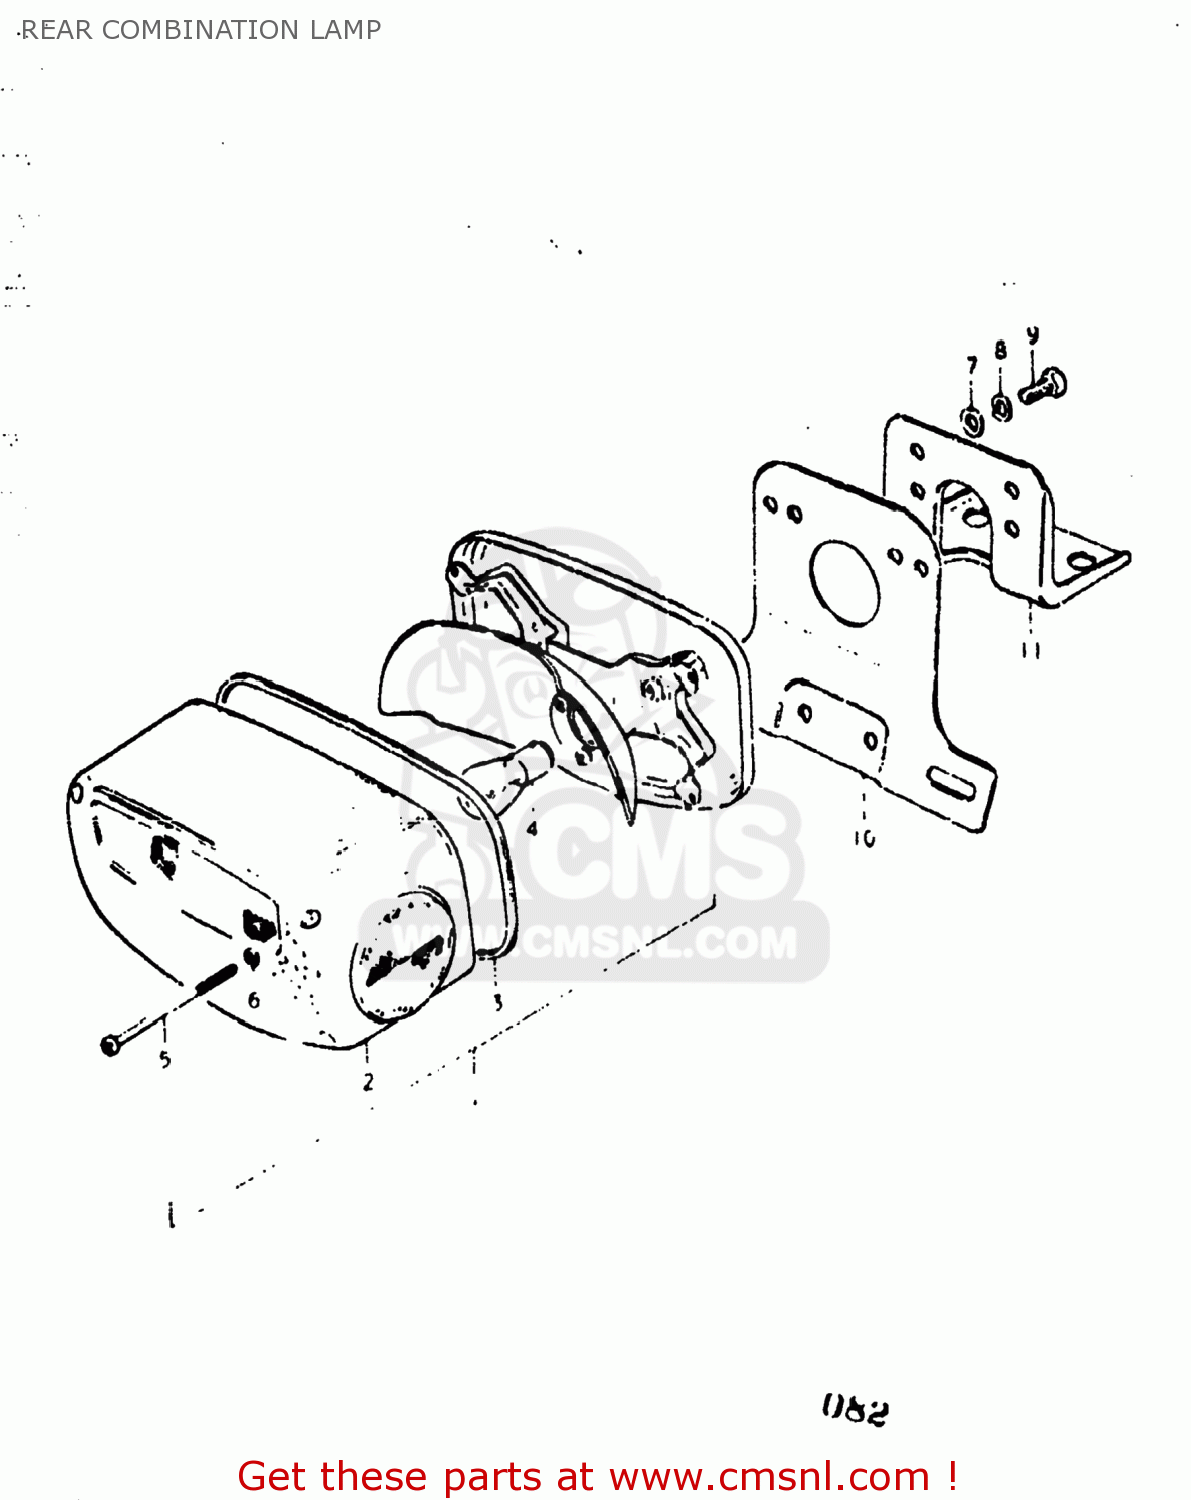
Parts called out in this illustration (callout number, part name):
1	LAMP ASSEMBLY,REAR COMBINATION
2	LENS,REAR COMBINATION LAMP
3	GASKET (NAS)
4	BULB(12V23W)
5	SCREW
6	GASKET (NAS)
7	WASHER
8	LOCK WASHER
9	BOLT
10	BRACKET,LICENSE PLATE
11	BRACKET,LICENSE PLATE
